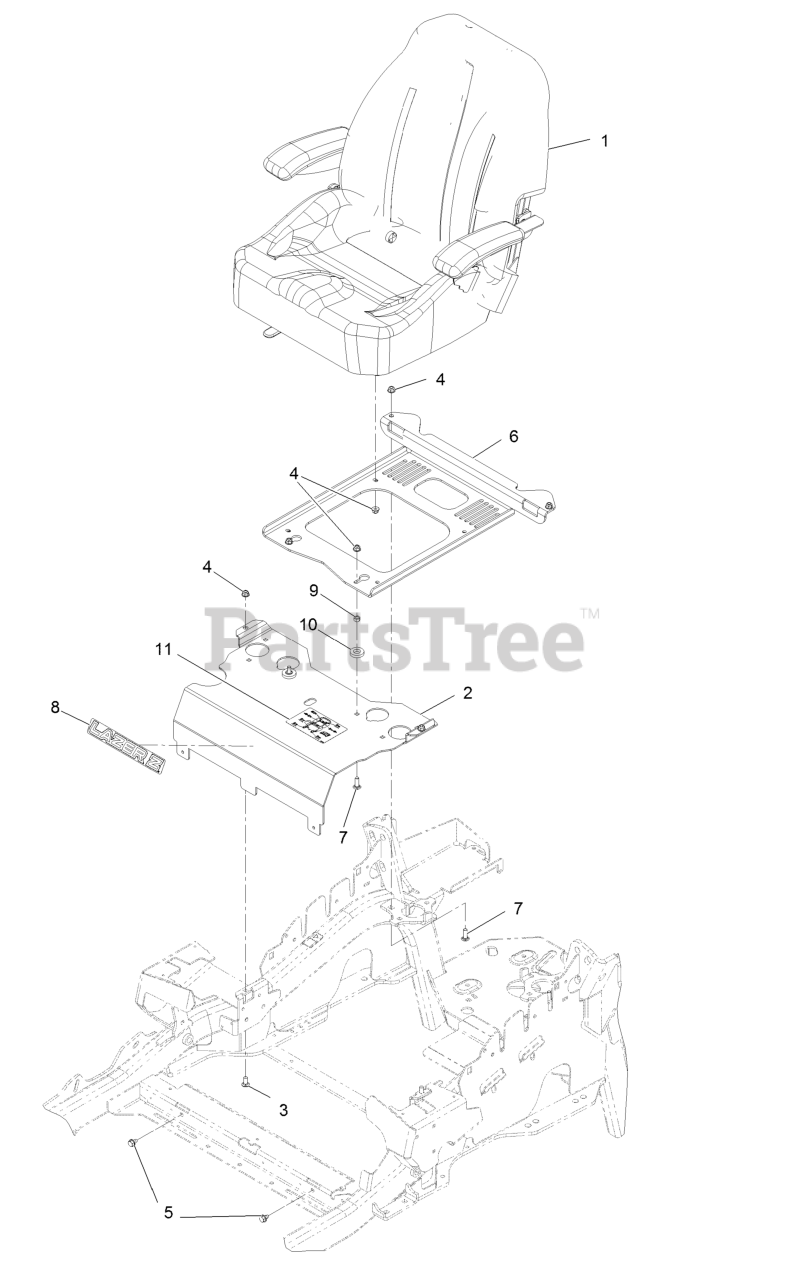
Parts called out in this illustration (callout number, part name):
1	ASM-Seat Lze
2	Panel-Front, Seat Mount
3	Bolt-Carriage 5/16-18 X 3/4 Short Neck
4	Nut-Nyloc 5/16-18 Flg
5	Screw-HWH 5/16 X 1/2 Tf
6	Plate-Support, Seat
7	Bolt-Carriage 5/16-18 X 1 Sp
8	Decal, Lazer Model
9	Nut-Hex 5/16-18
10	Spacer-Blade Drive
11	Decal-Service Aid
